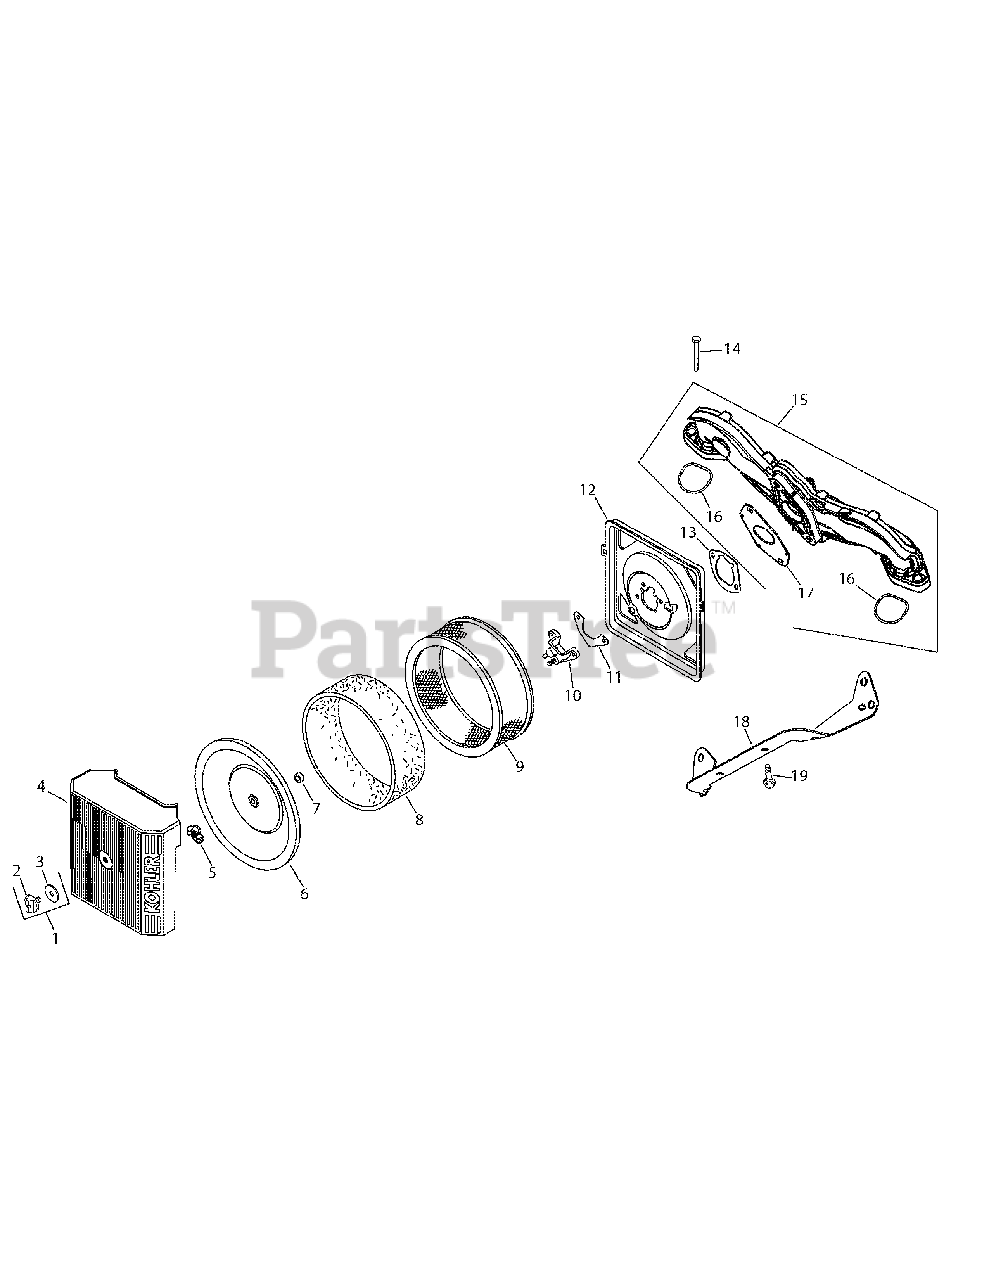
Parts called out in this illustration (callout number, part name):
1	Kit, Knob W/ Seal
4	Cover, Air Cleaner
6	Cover, Inner Air Cleaner
7	Seal, Inner Air Cleaner
8	Pre-Cleaner
9	Elements, Air Filter & Pre-Cleaner
10	Cup, Fuel Spitback W/ Nipple
11	Gasket, Fuel Spitback Cup
12	Base, Air Cleaner
13	Gasket, Air Cleaner Base
14	Manifold, Intake
15	Gasket, Carburetor
16	O-Ring, Intake Port
17	Screw, Flg M6x1.0x40
18	Bracket, Air Cleaner Base
19	Screw, Flg Thd Frm M5 x .8 x 10
20	Baffle, Spit-Back Cup
